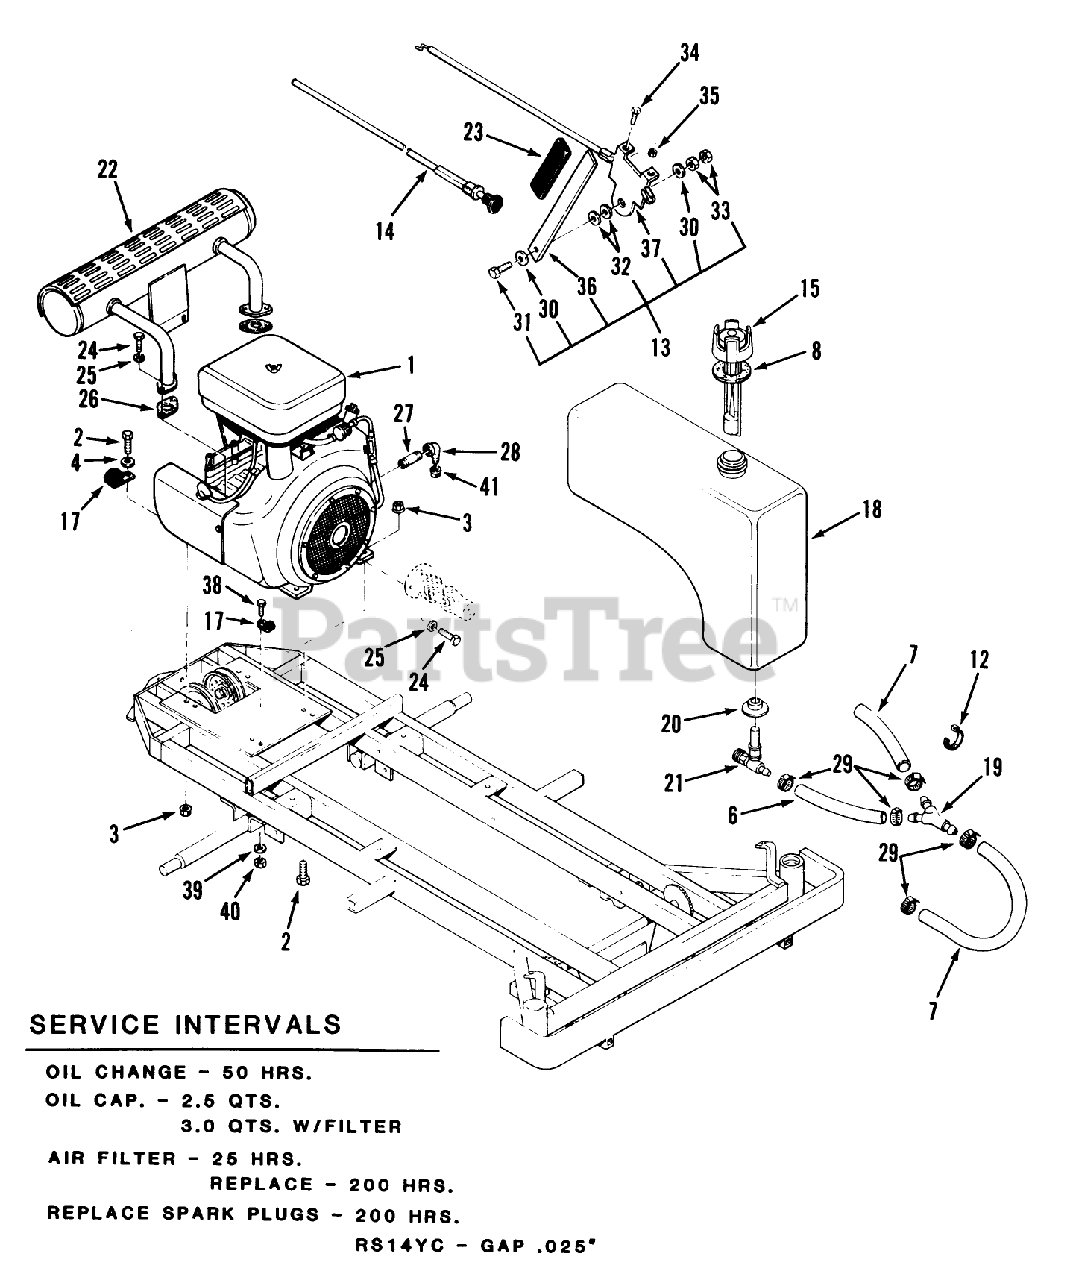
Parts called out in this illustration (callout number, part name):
1	Tire-Turf Tray, Front 12 X 7.5-8
2	BOLT
3	NUT
4	Washer
6	Hose5"
7	Fuel Line (29.5")
8	GASKET-GAS CAP
12	TIE-PLASTIC
13	Throttle Control (Includes items 30 thru 33, 36 & 37)
14	CABLE-CHOKE
15	Fuel Gauge Cap w/o Screw Vent (Includes item 8)
17	CLIP
18	Fuel Tank (Includes items 20 & 21)
19	FITTING-FUEL 45-Y
20	BUSHING
21	VALVE-FUEL
22	MUFFLER
23	GRIP BRAKE20258-K
24	Bolt
25	Lockwasher
26	Exhaust Gasket
27	Pipe
28	STREET-ELBOW 90 DEG
29	Clamp
30	SPRING-BELLEVILLE
31	HHCS
32	WASHER NYLON
33	LOCKNUT 5/16-18GR.B
34	Screw-Machine
35	Nut
36	HANDLE-THROTTLE B
37	CABLE-THROTTLE
38	Bolt
39	WASHER 5/16 SAE
40	Nut
41	Cap
42	Manual-Toro Power Plus Service
